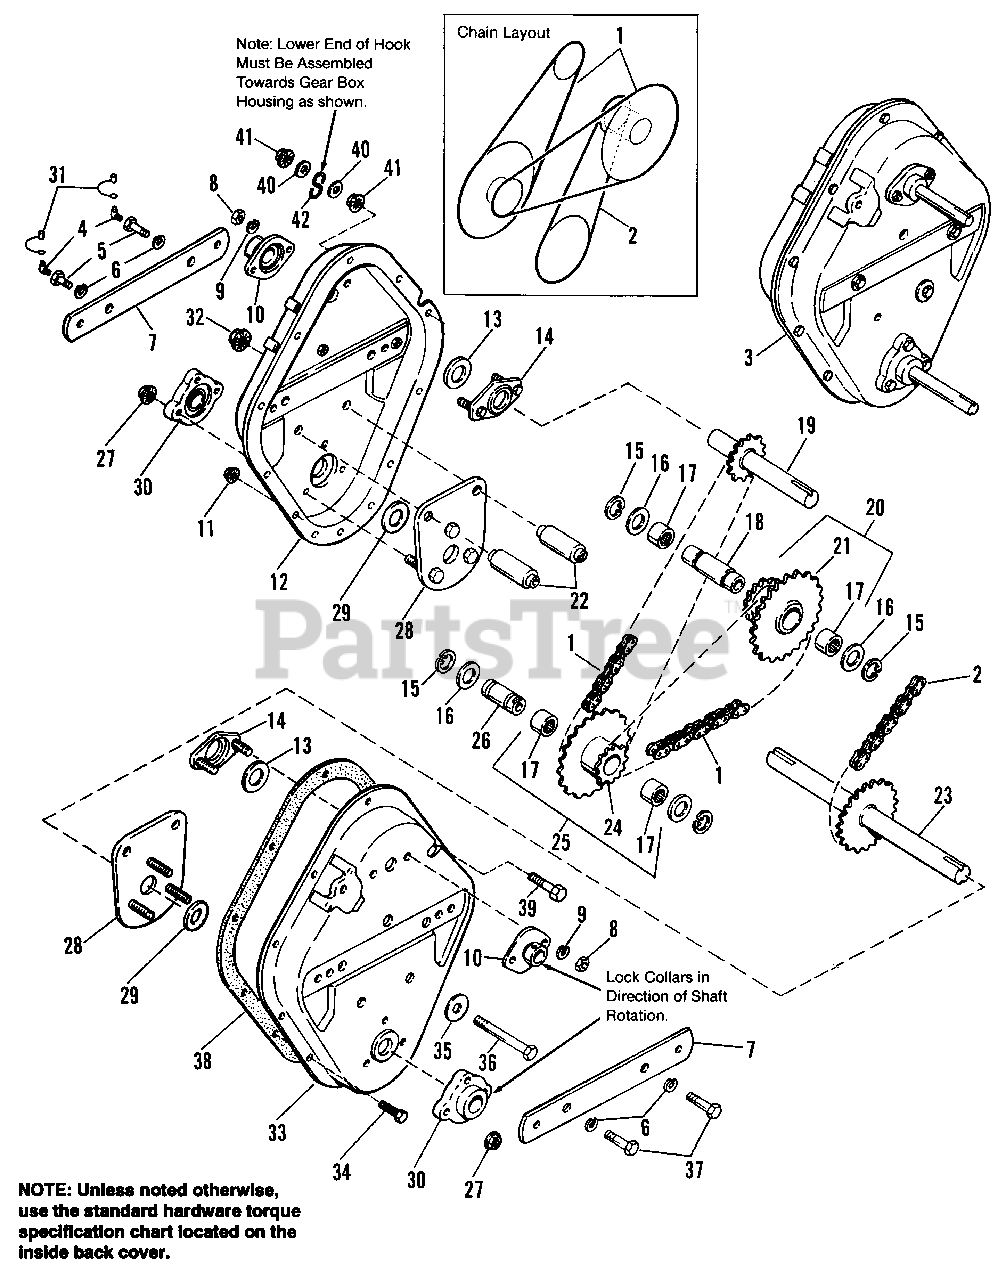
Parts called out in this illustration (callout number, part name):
3	TRANSMISSION SUB ASSY. (Includes Ref. Nos. 1-16, 18-38 on this page & Includes Ref. Nos.1-5, 7, 11, 17, 18, 19, 34, 36 & 38 in the 36" Tiller Drive Group)
4	FITTING, Grease
6	LOCKWASHER, 1/2
8	NUT, Hex, Full, 5/16-18
9	LOCKWASHER, 5/16
11	LOCKNUT, Hex, Full, 5/16-18
12	CASE ASSY., Half, R.H.
14	PLATE ASSY., Upper Bearing
15	RING, Retaining
17	BEARING, Roller
18	SPACER, Inter.
19	SHAFT ASSY., Pulley
20	SPROCKET & BEARING ASSY. (Includes Ref. Nos. 17 & 21)
22	SPACER
23	SHAFT ASSY., Tine
25	SPROCKET & BEARING ASSY. (Includes Ref. Nos. 17 & 24)
26	SPACER, Internal
27	LOCKNUT, Hex, Jam, 3/8-16
28	PLATE ASSY.
31	CAP, Grease
32	LOCKNUT, Flange, 1/2-13
33	CASE ASSY., Half, L.H.
34	CAPSCREW, Hex Hd., 5/16-18 x 5/8
35	WASHER, Plain, 1/2
36	CAPSCREW, Hex Hd., 1/2-13 x 4
37	CAPSCREW, Hex Hd., 1/2-20 x 1
39	CAPSCREW, Hex Hd., 5/16-18 x 1-1/4
40	WASHER, Flat
41	NUT, Hex, Flange, Lock, 5/16-18
